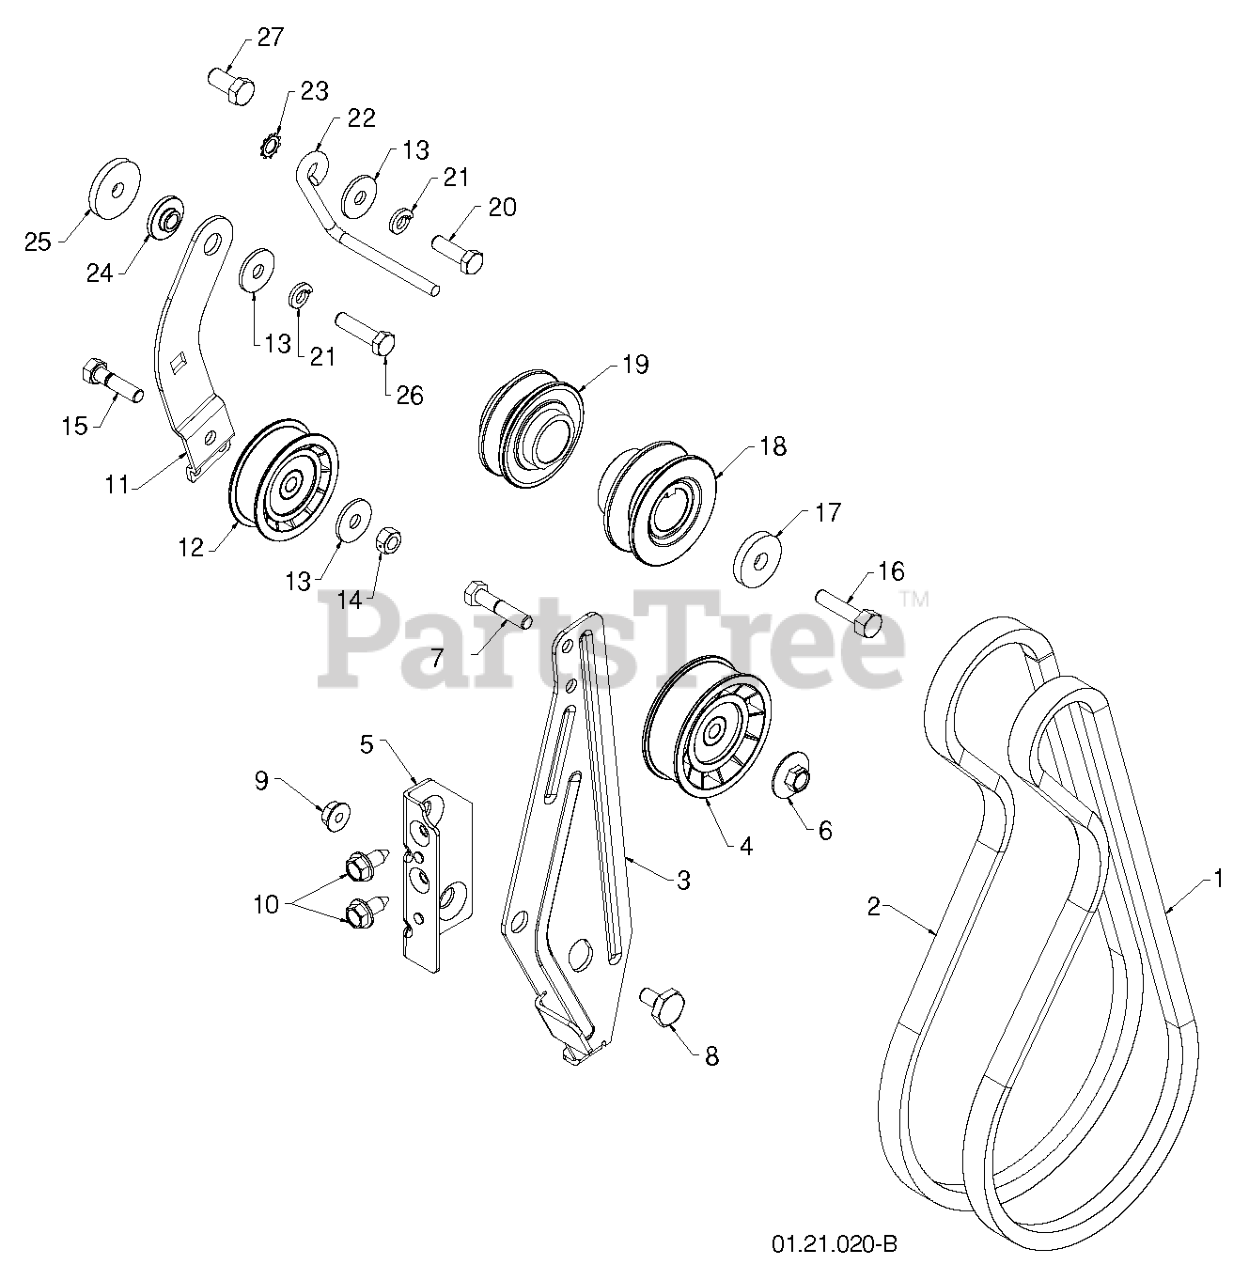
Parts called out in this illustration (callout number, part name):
1	V-BELT.IMPELLER
2	TRACTION BELT
3	ARM.IDLER.BRAKE.
4	PULLEY.W/SPACER.2.75
5	RP BRACKET.IDLER.PIVOT
6	NUT.FLANGE.HEX.5/16X18.BLACK
7	HEX BOLT
8	BOLT.SHOULDER.1/2X12
9	NUT.LOCK.5/16-18
10	BOLT.5/16HEX.WHS.HD
11	ARM, IDLER
12	PULLEY.W/SPACER.2.25
13	STEEL WASHER
14	NUT.71038.31-18.HEX.NYLOCK
15	BOLT.5/16-18X1-1/4 FULL.THREAD
16	SCREW, HEX HD 3/8-24 X 1-3/8
17	WASHER.400X1.25X5.
18	PULLEY ENG IMPELLER
19	PULLEY.ASM.ENG.TRACTION.1.00
21	WASHER.LOCK.HVY.HLCL.SPR.5/16
22	BELT.GUIDE.RH
23	WASHER EXT TOOTH LOCK 5/16
24	RP BUSHING, IDLER PIVOT
25	WASHER.FLAT.34X1.38X22
26	CAPSCREW.HEXHD.5/16X1.25.
27	SCREW.3/8-16 X .750 (2 2)
